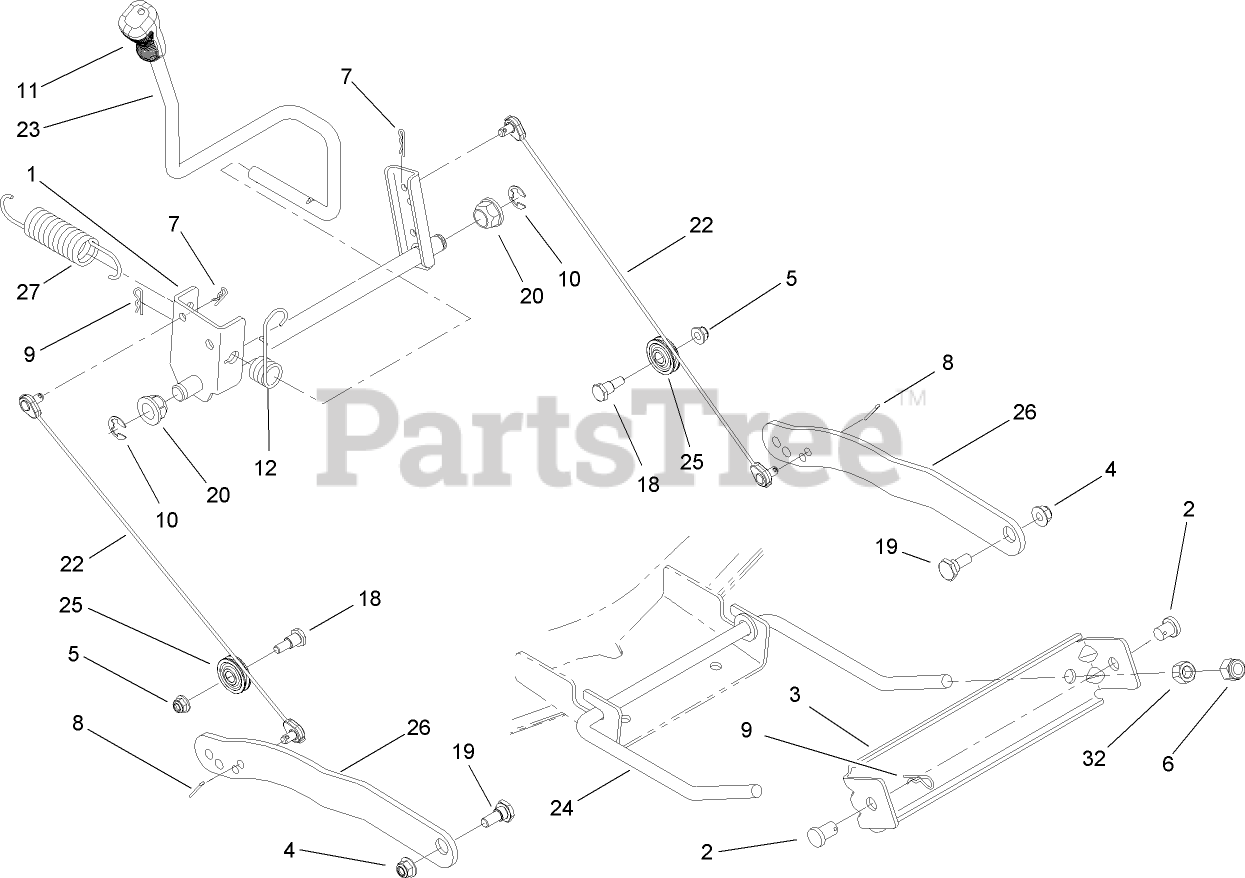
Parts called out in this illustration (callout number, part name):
1	LIFT SHAFT ASM
2	PIN-BRACKET, LIFT
3	BRACKET-STABILIZER
4	NUT-LOCK, FLANGE
5	NUT-LOCK, FLANGE
6	NUT-LOCK, HEX (NYLON)
7	PIN-COTTER
8	PIN-COTTER
9	PIN-HAIR
10	RING-E
11	GRIP-HANDLE
12	SPRING-TORSION
18	BOLT-SHOULDER
19	BOLT-SHOULDER
20	BEARING-FLANGE
22	CABLE-LIFT
23	HANDLE-LIFT
24	ROD-FRONT, ADJUST
25	PULLEY-ROLLER
26	LINK-DECK, LIFT
27	SPRING-LIFT, ASSIST
32	NUT-HEX
